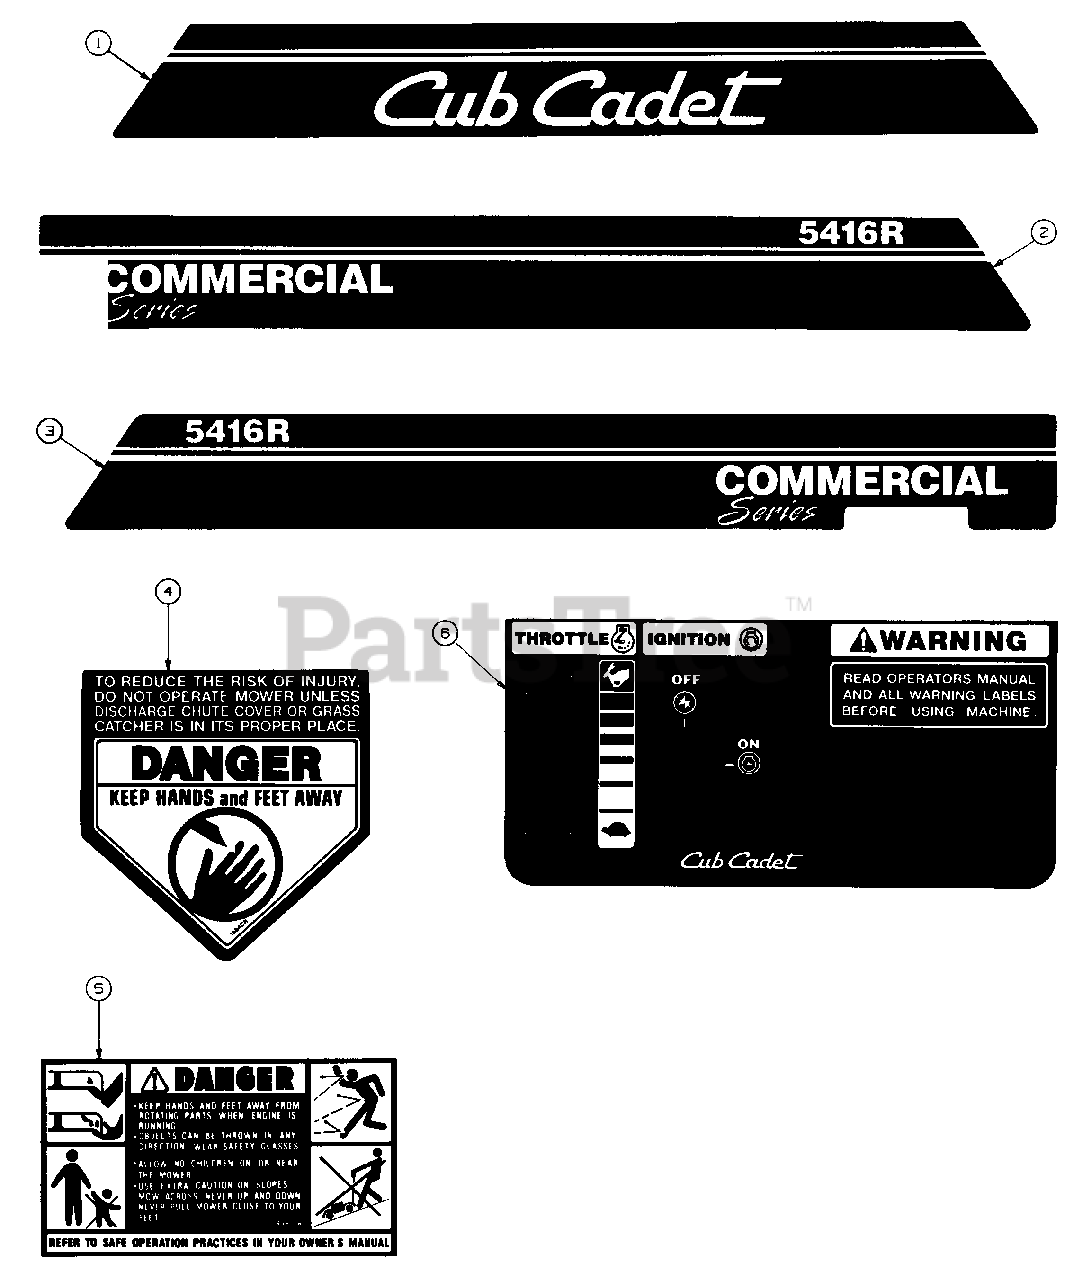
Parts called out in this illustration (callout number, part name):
1	Graphic, Belt CoVQr Front
2	Graphic 5416R, Belt Cover Right
3	Graphic 541 6R, Belt Cover Left
4	Graphic, Danger Cut Finger
5	Graphic, Danger
6	Graphic, Control Panel
